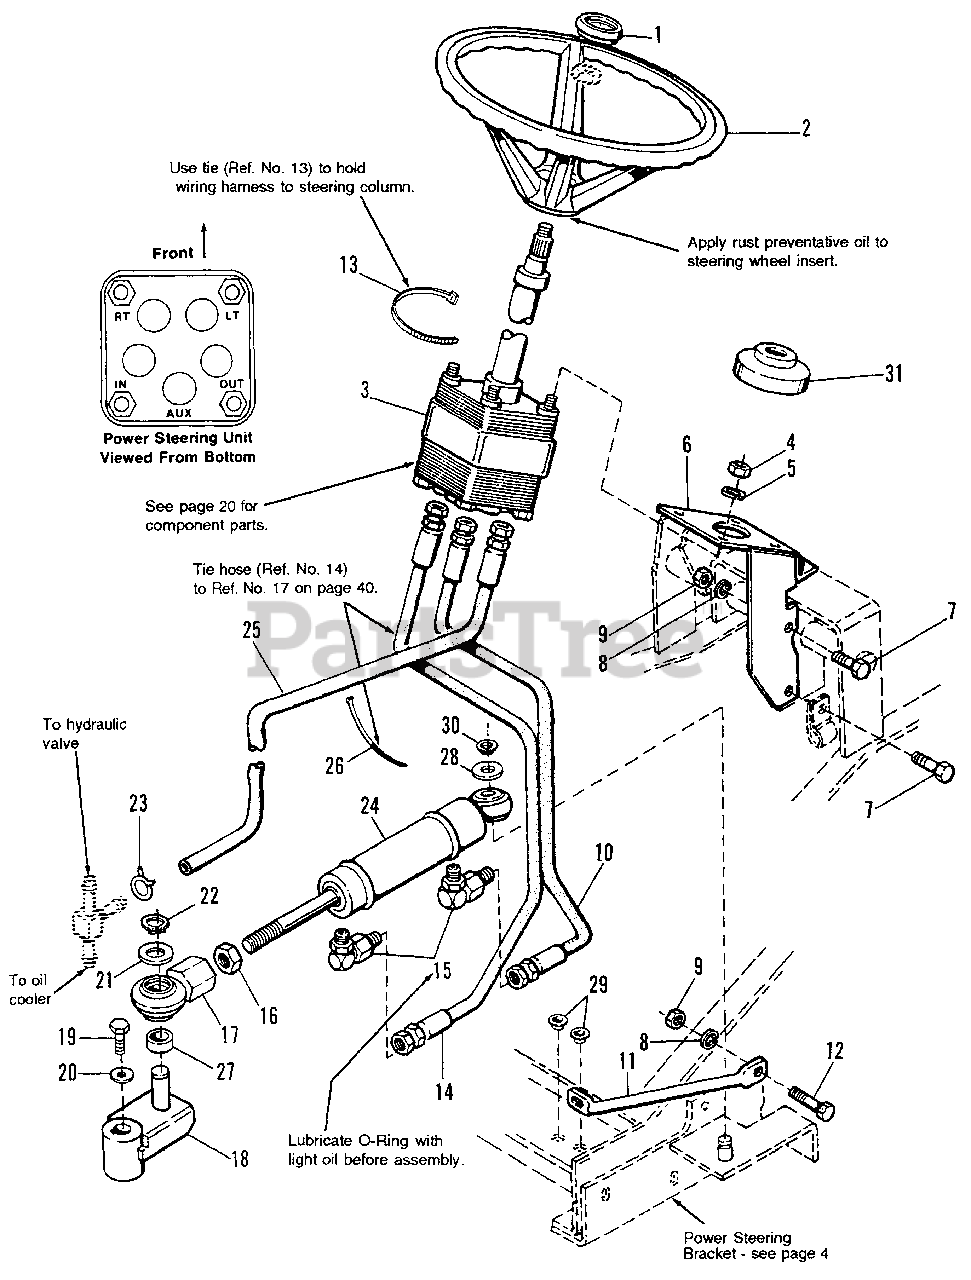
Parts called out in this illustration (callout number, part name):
1	CAP, Steering Wheel
2	WHEEL ASSY., Steering
3	STEERING UNIT, Hydrostatic (See page 20 for components.)
4	NUT, Hex, 5/16-24
5	LOCKWASHER, 5/16
6	SUPPORT ASSY., Steering Valve
7	CAPSCREW, Hex Hd., 3/8-16 X 1, Gr. 5
8	LOCKWASHER 3/8
9	NUT, Hex, 3/8-16
10	HOSE ASSY., Hyd. (Valve to Cyl.)
11	BRACE, Cylinder
12	CAPSCREW, Hex Hd., 3/8-16 x 1-1/2, Gr. 5
14	HOSE ASSY., Hyd. (Valve to Cyl.)
15	FITTING, Hyd., 9/16-18 x 9/16-18 - 90 degree
16	NUT, Hex, 3/4-16
17	BALL JOINT ASSY. (Inc. Ref. Nos. 20, 27, 28 & 30)
18	ARM ASSY., Steering
19	CAPSCREW, Hex Hd., 3/8-16 x 7/8
20	WASHER, 13/32 x 1 1/4 x 3/16
21	WASHER, 3/4 x 1 3/8
22	RING, Retaining, 3/4
24	CYLINDER, Power Steering
25	HOSE ASSY., Hyd., (Valve to Cooler)
26	TIE, Self-Locking
27	SPACER
28	WASHER, 5/8 x 1
29	PLUG, Plastic
30	RING, Retaining, 5/8
31	BOOT, Steering Arm
